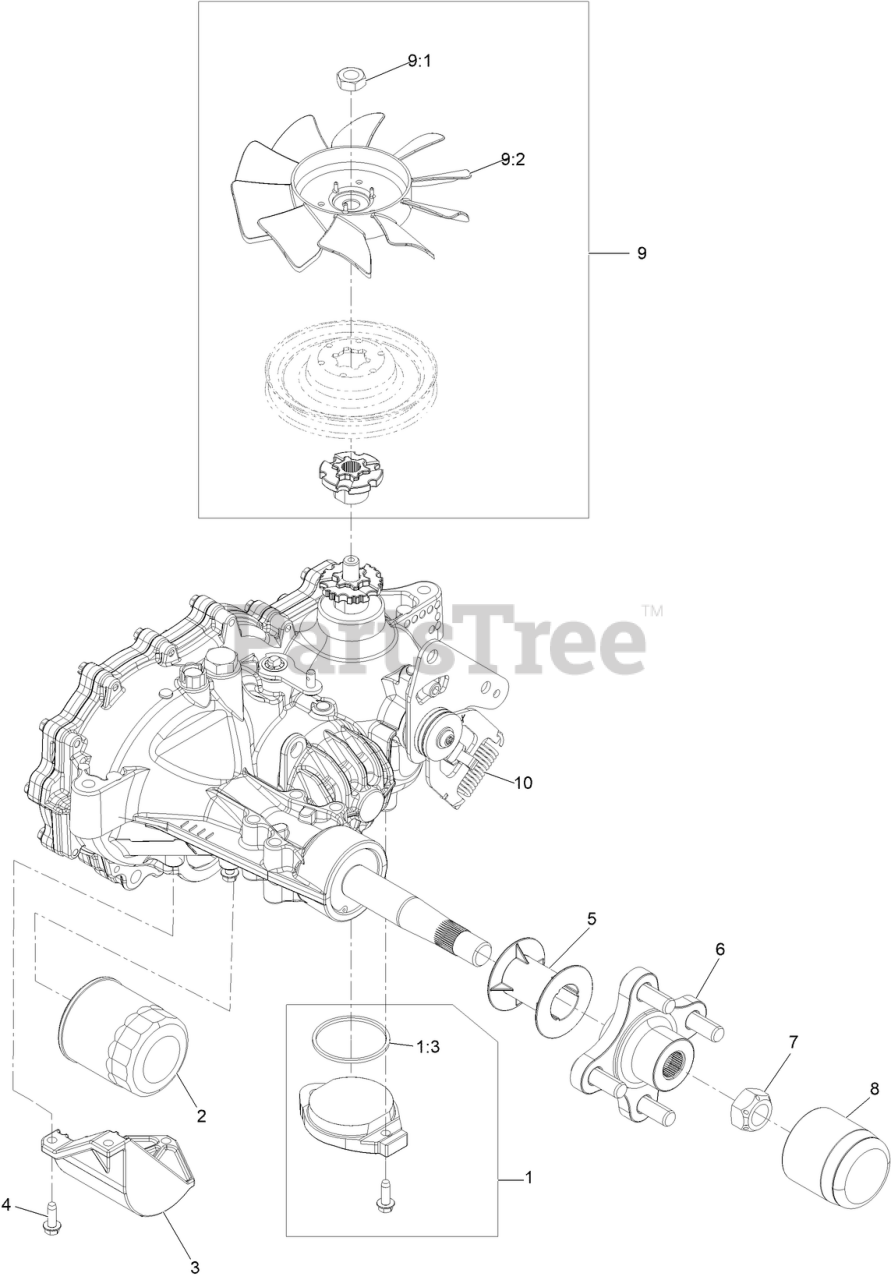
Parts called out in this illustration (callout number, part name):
1	CHARGE KIT
1:3	O RING-SEAL
2	ELEMENT-OIL FILTER, HYD
3	GUARD-FILTER, RH
5	TUBE-AXLE
6	HUB-OFFSET
7	NUT-HUB
8	CAP-AXLE, LONG
9	Fan And Pulley Kit
10	SPRING-EXTENSION
